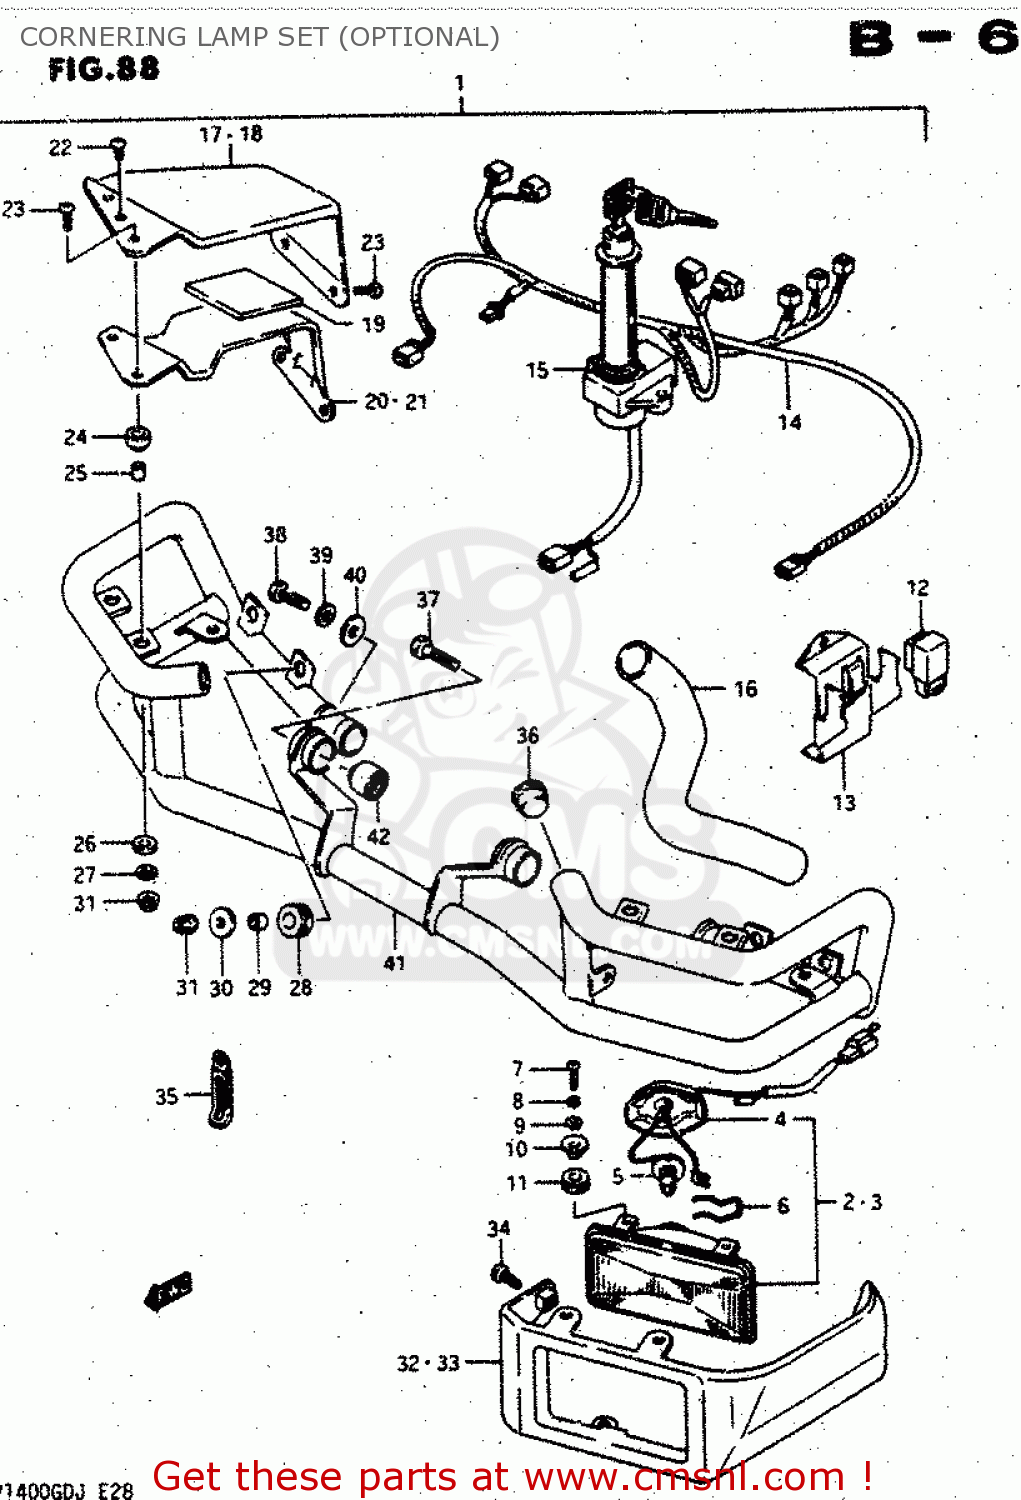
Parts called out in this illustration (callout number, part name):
1	LAMP SET,CORNERING
2	LAMP ASSEMBLY,CORNERING,RIGHT
3	LAMP ASSEMBLY,CORNERING,LEFT
4	SOCKET
5	BULB 12V 35W H3
6	SPRING
7	SCREW
8	LOCK WASHER
9	WASHER
10	SPACER(4.2X8X9)
11	CUSHION
12	RELAY,NEUTRAL STARTER
13	BRACKET, RELAY
14	WIRE
15	SWITCH ASSEMBLY,IGNITION
16	HOSE,RADIATOR OUTLET
17	COVER,CORNER LAMP,RIGHT
18	COVER,CORNER LAMP,LEFT
19	CUSHION,CORNER LAMP CVR CTR
20	COVER,CORNER LAMP,LOWER
21	COVER,CORNER LAMP,LOWER
22	SCREW
23	SCREW
24	CUSHION
25	SPACER
26	CUSHION
27	WASHER (5.5X14X1.2)
28	CUSHION
29	SPACER(6.1X9X7.5)
30	WASHER (5.5X20X1.2)
31	NUT
32	COVER COMP,ACCESSORY B
33	COVER COMP,ACCESSORY B
34	SCREW(5X10)
35	CLAMP
36	CAP,ACCESSORY BAR
37	BOLT
38	BOLT
39	WASHER
40	WASHER (8.2X24X1.6)
41	BAR SET,ACCESSORY
42	BUSH
